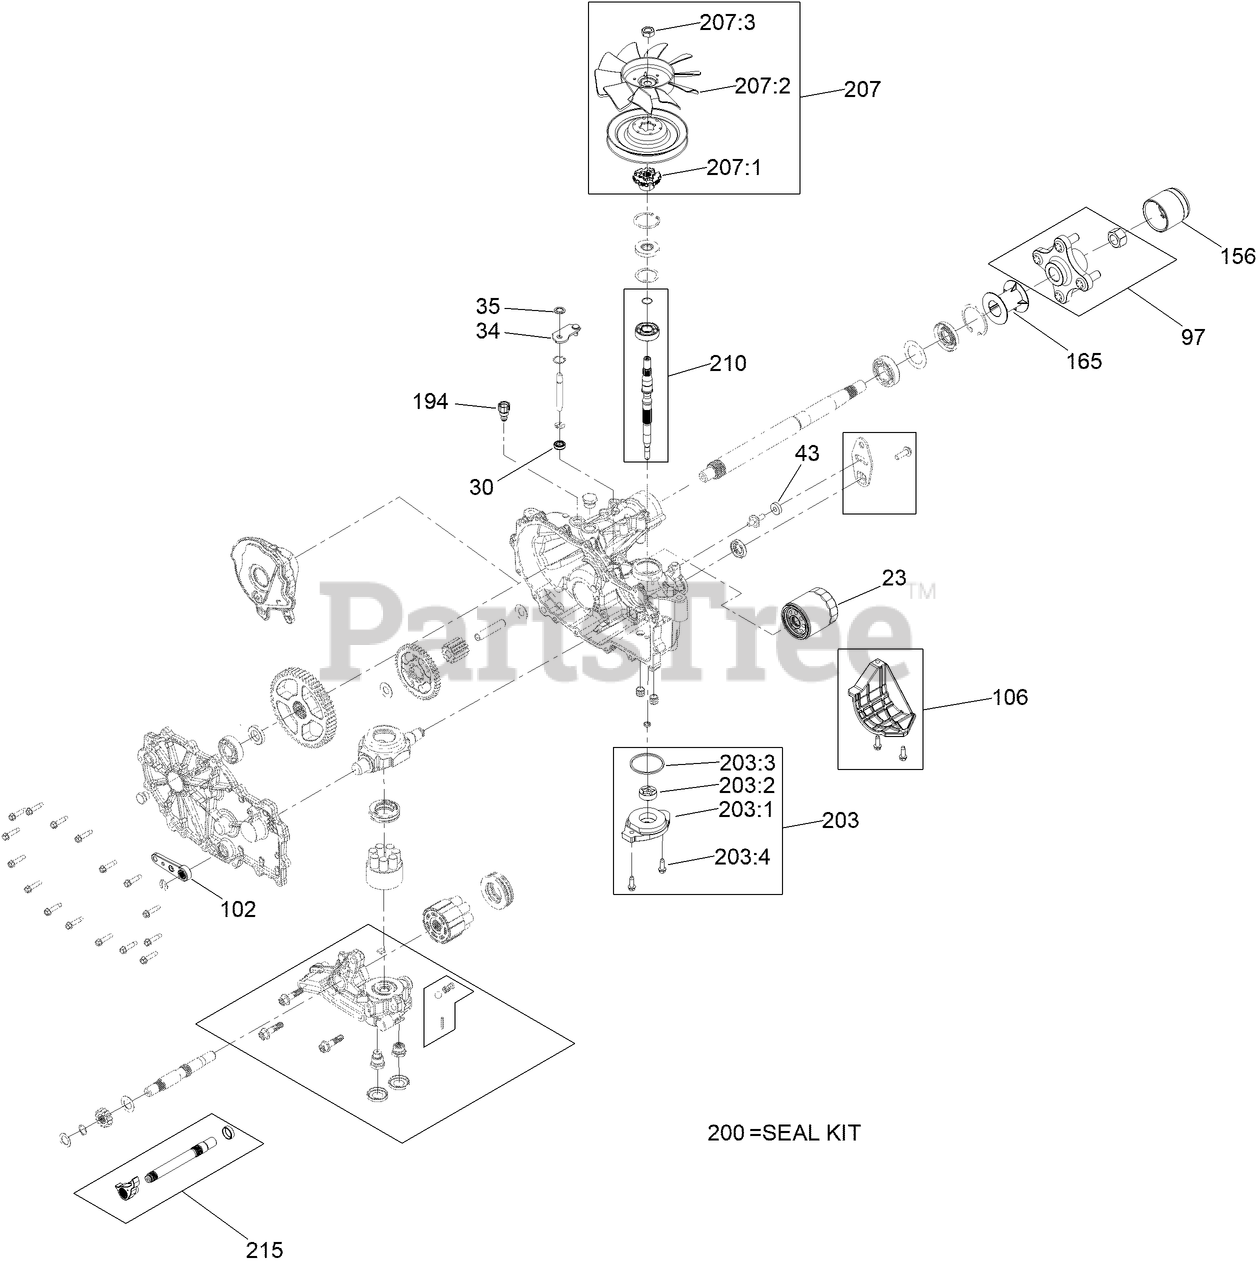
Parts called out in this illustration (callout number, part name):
23	ELEMENT-OIL FILTER, HYD
30	SEAL-LIP
34	ARM-BYPASS
35	RING-RETAINING, EXTERNAL
43	PUCK-FRICTION
97	HUB-OFFSET
102	HANDLE-BRAKE
106	GUARD-FILTER, LH
156	CAP-AXLE, LONG
165	TUBE-AXLE
194	ASSEMBLY-FITTING, BREATHER
200	SEAL KIT
203	CHARGE KIT
203:1	COVER-CHARGE PUMP
203:2	GEROTOR ASM
203:3	O RING-SEAL
207	FAN AND PULLEY KIT
207:1	HUB-FAN
207:3	NUT-HJ
210	INPUT SHAFT KIT
215	INBOARD KIT
